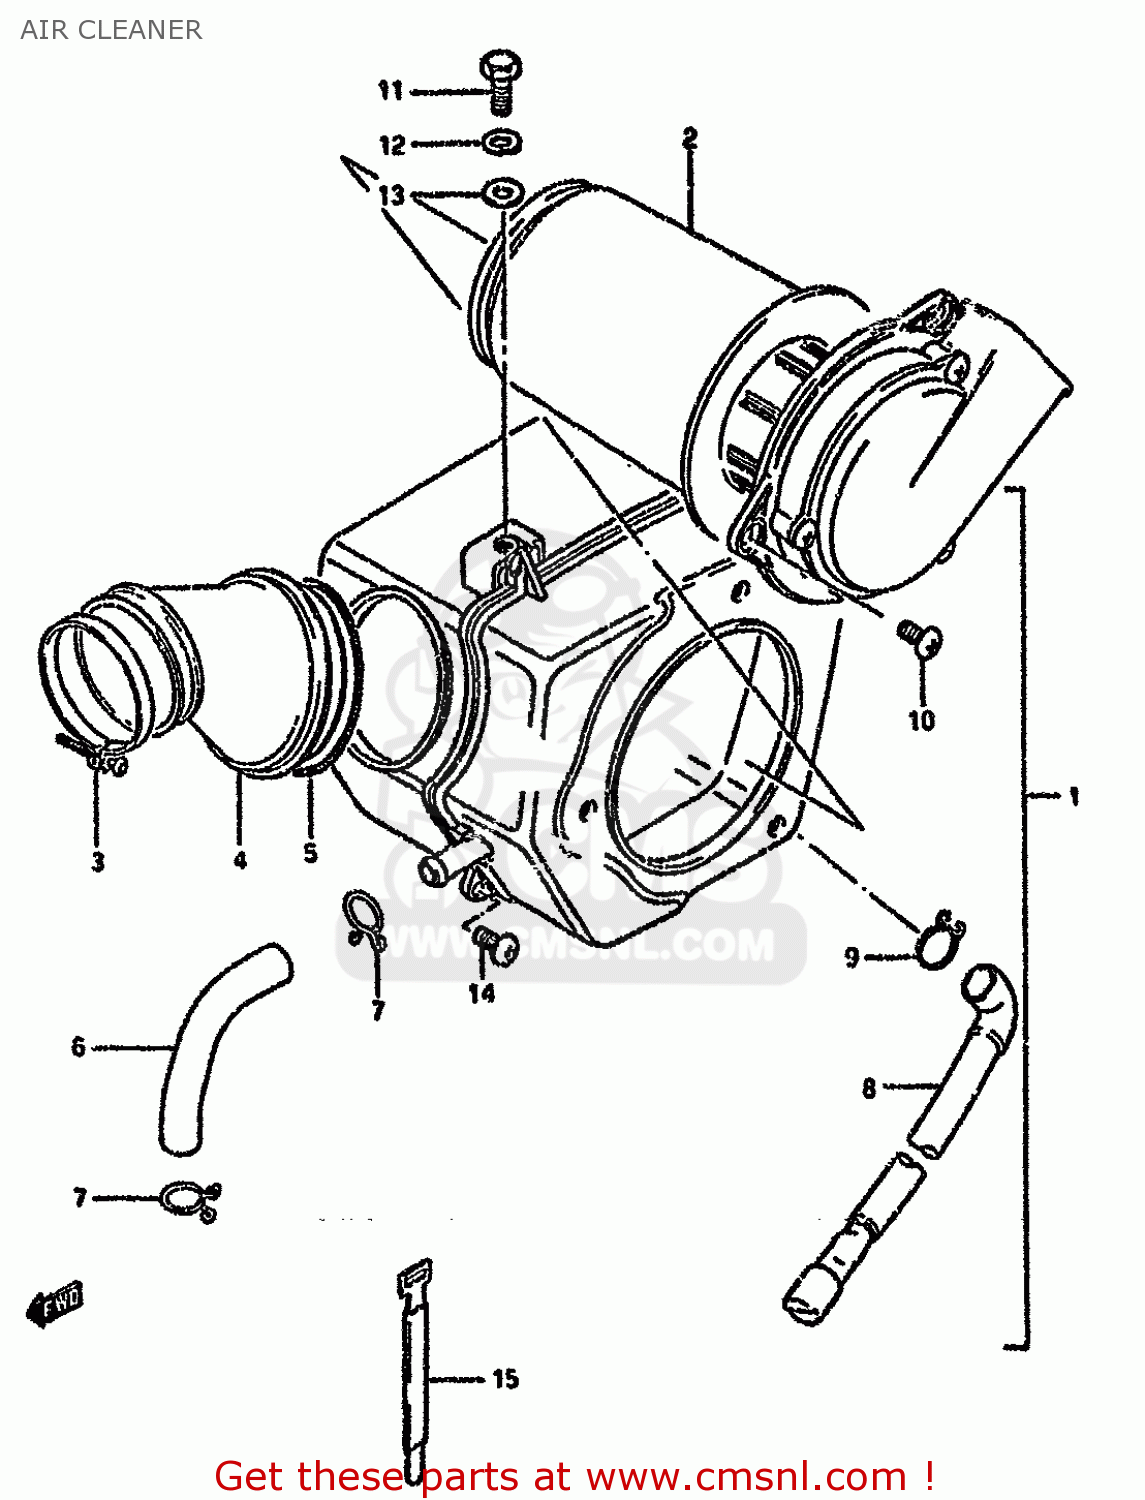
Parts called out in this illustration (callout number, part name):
1	CLEANER ASSY,AIR
2	FILTER
3	CLAMP
4	TUBE,OUTLET
5	CLAMP,AIR CLEANER SIDE
6	TUBE,BREATHER
7	CLIP
8	TUBE,DRAIN
9	CLIP
10	SCREW
11	BOLT
12	WASHER,LOCK
13	WASHER
14	SCREW
15	CLAMP L:110
